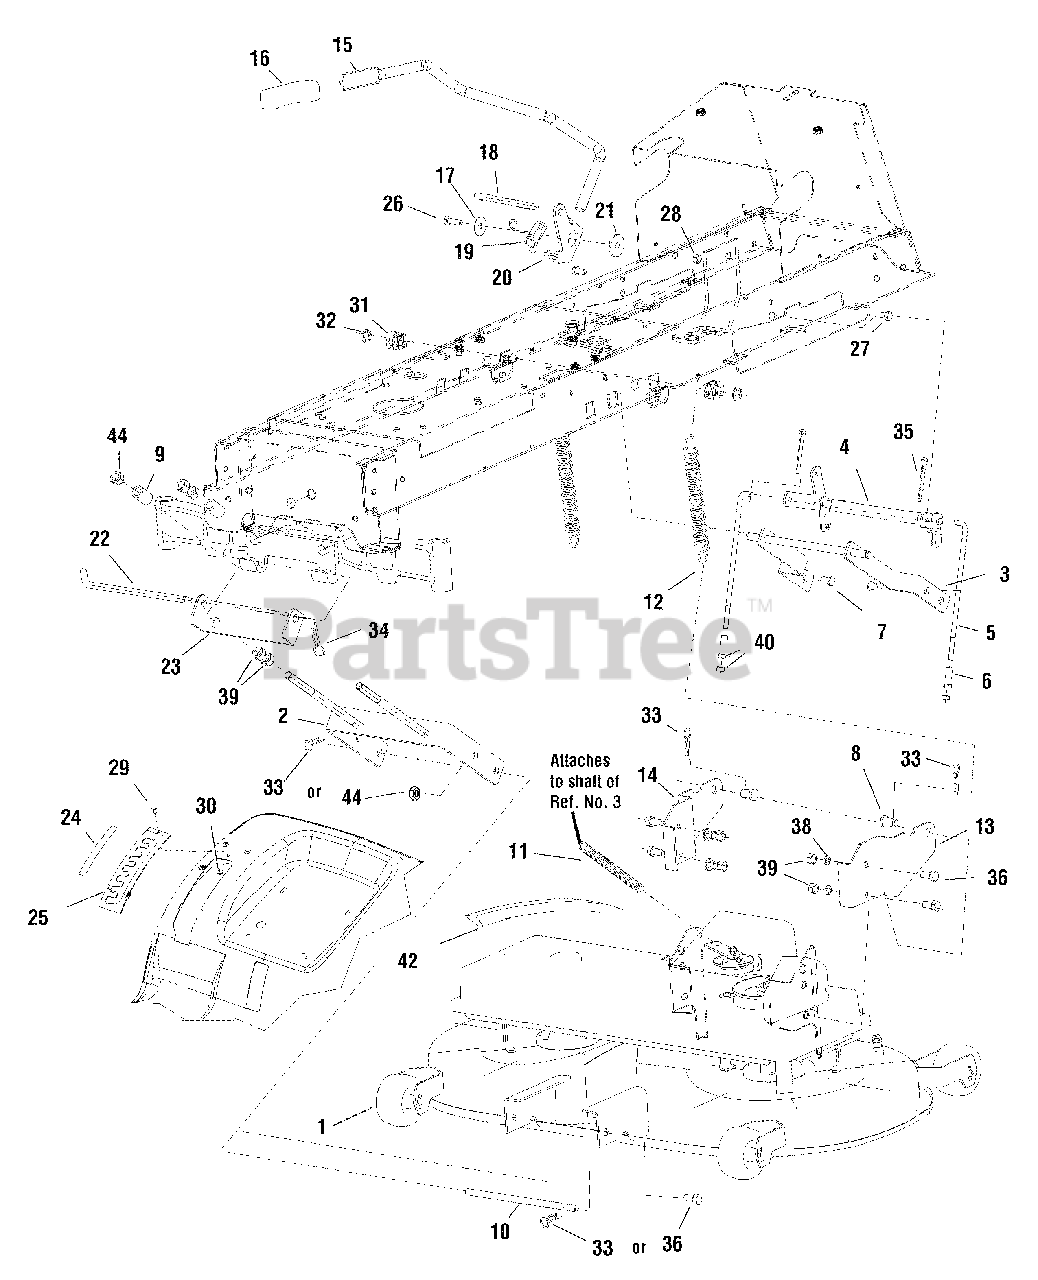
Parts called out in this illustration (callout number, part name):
1	MOWING MECHANISM
2	HINGE, Front
3	ARM, Lift
4	ROD, Lift
5	TIE ROD, Lift 0-8040-311
6	DISTANCE, Lift 0-9521-289
7	PIN, 0-9016-463
8	PIN, Mowing 1-9310-417
9	DISTANCE, Lift Hitch 0-9521-290
10	STUD
11	SPRING, 0-9746-460
12	SPRING, 0-9746-483
13	HANDLE, Extend, Left
14	HANDLE, Extend, Right
15	ROD, Lift
16	GRIP, Black
17	WASHER, 5/16
18	ROD, Lift 3/8 dia
19	SPRING, Torsion
20	CLEVIS, Lift
21	SPACER, Pivot
22	PIN, Hitch
23	HANGER, Front
24	DECAL, Height of Cut
25	QUADRANT, Lift Height
26	CAPSCREW, Hex Head, 5/16-18 x 1
27	CAPSCREW, Hex Head, 5/16-18 x 5/8
28	NUT, Hex Flange Lock, 5/16-18
29	BOLT, Carriage, 1/4-20 x 5/8
30	NUT, Hex Flange Whiz, 1/4-20
31	BUSHING, 0-9462-202
32	LOCK RING, 12
33	PIN, Flexible 0-9245-240
34	CLIP, Pin Safety
35	SPINDLE
36	BOLT, M12 x 30
38	WASHER, 12
39	NUT, M12
39	NUT, Flange Lock, M12
40	NUT, M10
42	V-BELT, Li, 17 x 1200
44	NUT, M12
